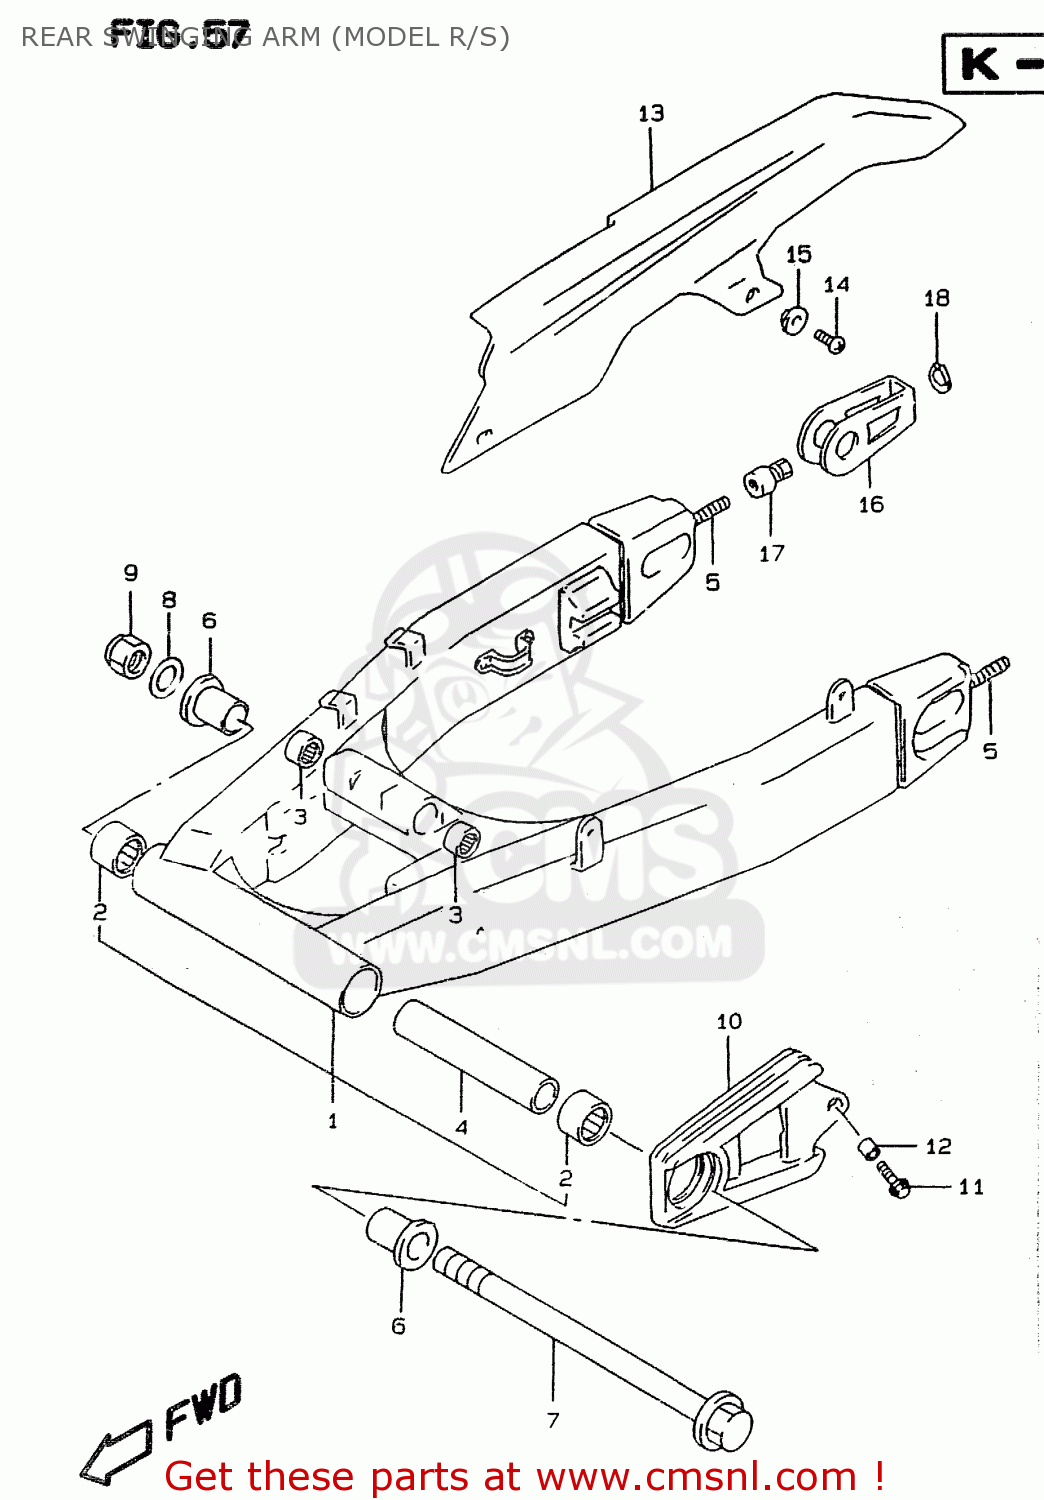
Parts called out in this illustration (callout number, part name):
1	SWINGINGARM ASSY,RR
2	BEARING(25X33X35)
3	BEARING(17X24X25)
4	SPACER,RR SWGARM PIVOT CTR
5	STUD,CHAIN ADJUSTER BOLT
6	SPACER,RR SWGARM PIVOT BERRING
7	SHAFT,RR SWINGINGARM PIVOT
8	WASHER (18.2X28X2.6)
9	NUT
10	BUFFER,CHAIN TOUCH DEFENSE
11	BOLT 6X20,WITH PLAIN WASHER
12	SPACER
13	CASE,CHAIN
14	SCREW 6X12
15	WASHER
16	ADJUSTER,CHAIN
17	ADJUSTER,CHAIN
18	CIRCLIP
